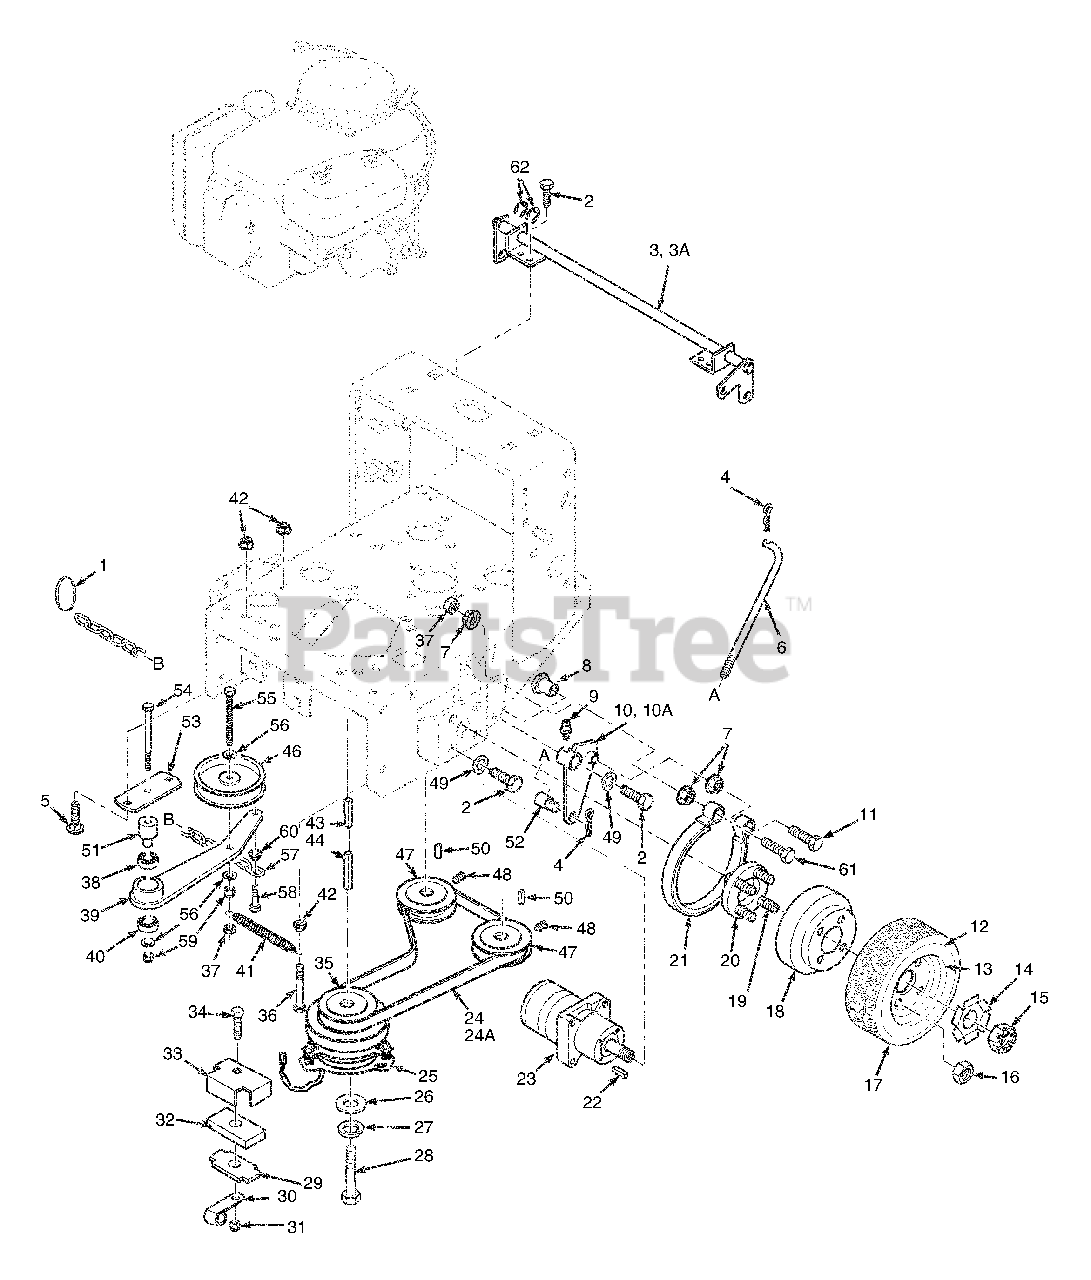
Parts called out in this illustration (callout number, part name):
1	Ring, Split
2	Bolt, 3/8-16 x 1" Hex Head
3A	Brake Shaft Assembly (20" Small Frame)
4	Hair Pin Cotter, .094 x 1.62
5	Carriage Bolt, 5/16-18 x 3/4"
6	Rod, Brake Lower
7	Nut, 3/8-16 Serr. Flange
8	Bushing, Brake
9	Grease Fitting
10	Brake Actuator Wlmt., LH
10A	Brake Actuator Wlmt., RH
11	Bolt, 3/8-16 x 2-1/4"
12	Tire, 18 x 8.50, 4 ply
13	Rim Assy
14	Lock Washer, Wheel Motor
15	Hex Castle Nut, 3/4-16 UNF
16	Nut, Lug
17	Wheel Assy.,
18	Brake Drum
19	1/2-20 Serrated Bolt
20	Hub, Wheel
21	Brake Band, 7.5"
22	Key, 3/16" X 3/4" Woodruff
23	Wheel Motor
24A	Belt, Pump Drive (20" Frame)
25	Electric Clutch
26	Flat Washer .469 x 1.75 x .25
27	Lock Washer, 7/16"
28	Hex Head Bolt, 7/16-20 x 2-3/4"
29	Plate, Backing
31	Nut, 5/16-18 Elastic Stop
32	Rubber Pad, Clutch Stop
33	Retainer, Clutch Stop
34	Hex Head Bolt, 5/16-18 x 1-3/4"
35	Pulley, Pump Drive Engine
36	Hex Head Bolt, 5/16-18 x 2-3/4"
37	Nut, 3/8-16 Center Lock
38	Ball Bearings
39	Idler Arm Assembly
40	Ball Bearings
41	Spring, Pump Belt Idler
42	Nut, 5/16-18 Serr. Flange
43	Key, 1/4" x 1/4" x 1" Clutch Mtg.
44	Key, 1/4" x 1/4" x 2-3/4" Pulley Mtg.
45	Flat Washer, 3/8"
46	Pulley, Idler 4.5"
47	Pulley, Pump Shaft
48	Setscrew, 5/16-18 x 3/8"
49	Lockwasher, 3/8"
50	Key, 5.0 x 5.0 x 25mm
51	Pivot, Idler (Long)
52	Swivel Joint
53	Base, Idler Pivot
54	Bolt, Hex Head 3/8-16 x 3"
55	Bolt, Hex Head 3/8-16 x 2-3/4"
56	Flatwasher 3/8"
57	Chain
58	Bolt, Hex Head 1/4-20 x 1-1/4"
59	Nut, Hex Elastic Stop 3/8-16
60	Nut, Serrated Flange 1/4-20
61	Bolt, Hex Head 3/8-16 x 2-1/4"
62	Retaining Ring, 3/4" Ext. "E"
